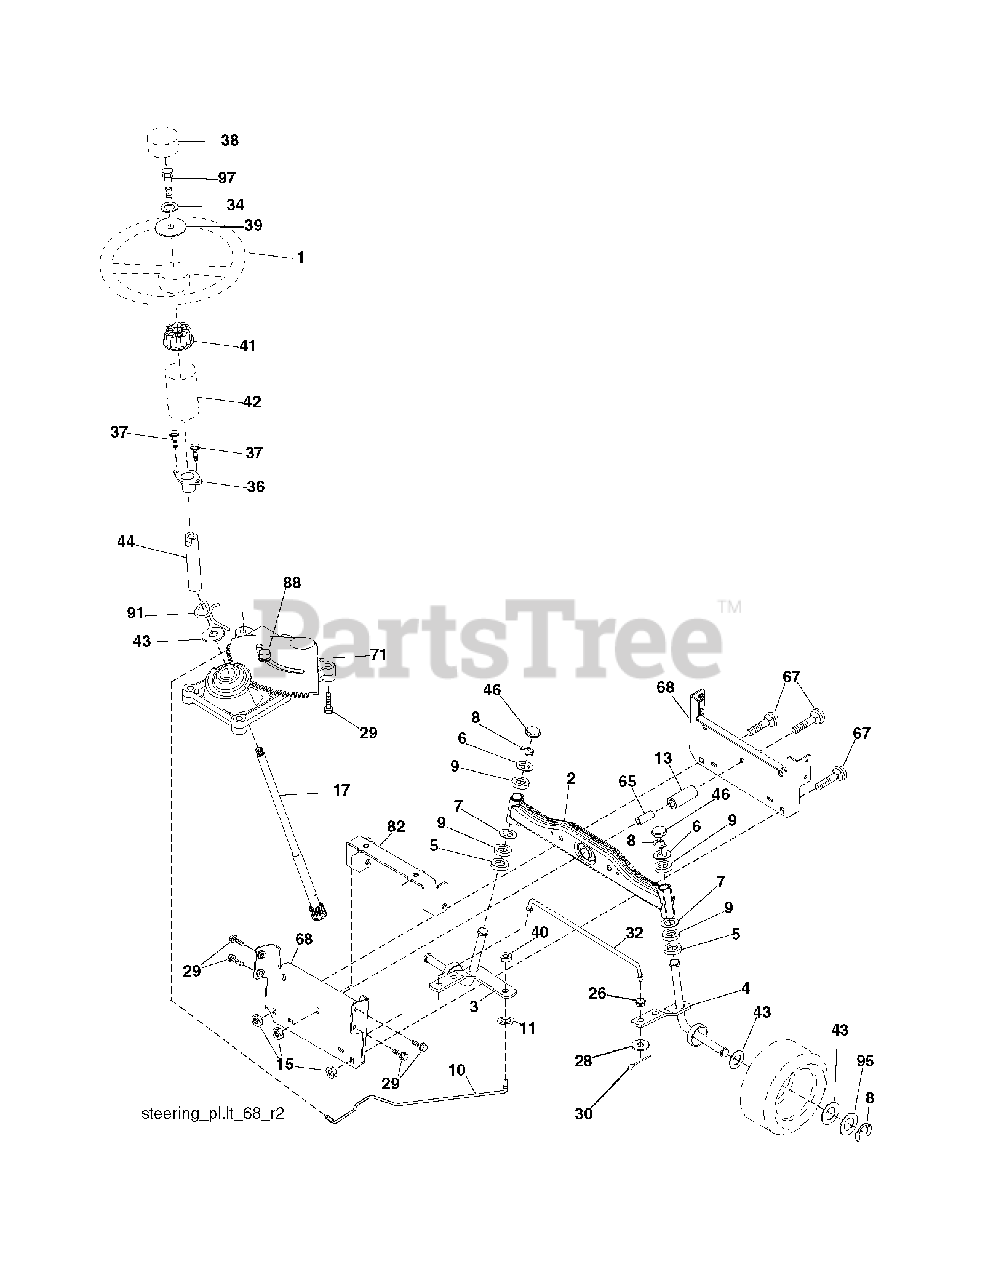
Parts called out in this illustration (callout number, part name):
1	WHEEL.STEERING.OPP.BLACK
2	AXLE HALF ASM-WELDED
3	SPINDLE.ASM.LH.15"TIRES
4	SPINDLE.ASM.RH.15"TIRES
9	BRNG T
10	DRAGLINK.15".TIRES.2001
11	WASHER, LOCK 3/8
13	TUBE, PIVOT AXLE
15	NUT LOCK FLG 3/8-16 UNC
17	SHAFT STEERING SPLINE
26	BUSHING.DRAGLINK
28	WASHER
29	SCREW, 3/8-16X3/4
30	COTTER PIN
32	ROD.TIE.WIRE.FORM
34	LOCKWASHER
36	BUSHING, STEERING
38	CAP.WHEEL.STEER.OPP.BLK
39	WASHER.11/32
40	NUT CROWNLOCK 3/8-24
41	ADAPTER, WHEEL STNG..
42	BOOT.STEERING.SHAFT.BLACK
44	SHAFT.EXTEN.STRG.SPLINE
65	SPACER.BRACE.AXLE
67	BOLT CARRIAGE
68	BRACE.AXLE.15"TIRES
71	STEERING ASM
82	BRACKET.SUSP.CHASSIS.FRONT.15
88	BOLT, SHOULDER 7/16-20
91	CLIP.STEERING
95	WASHER.HARDENED
97	BOLT 5/16-18 X 4 W/PATCH
